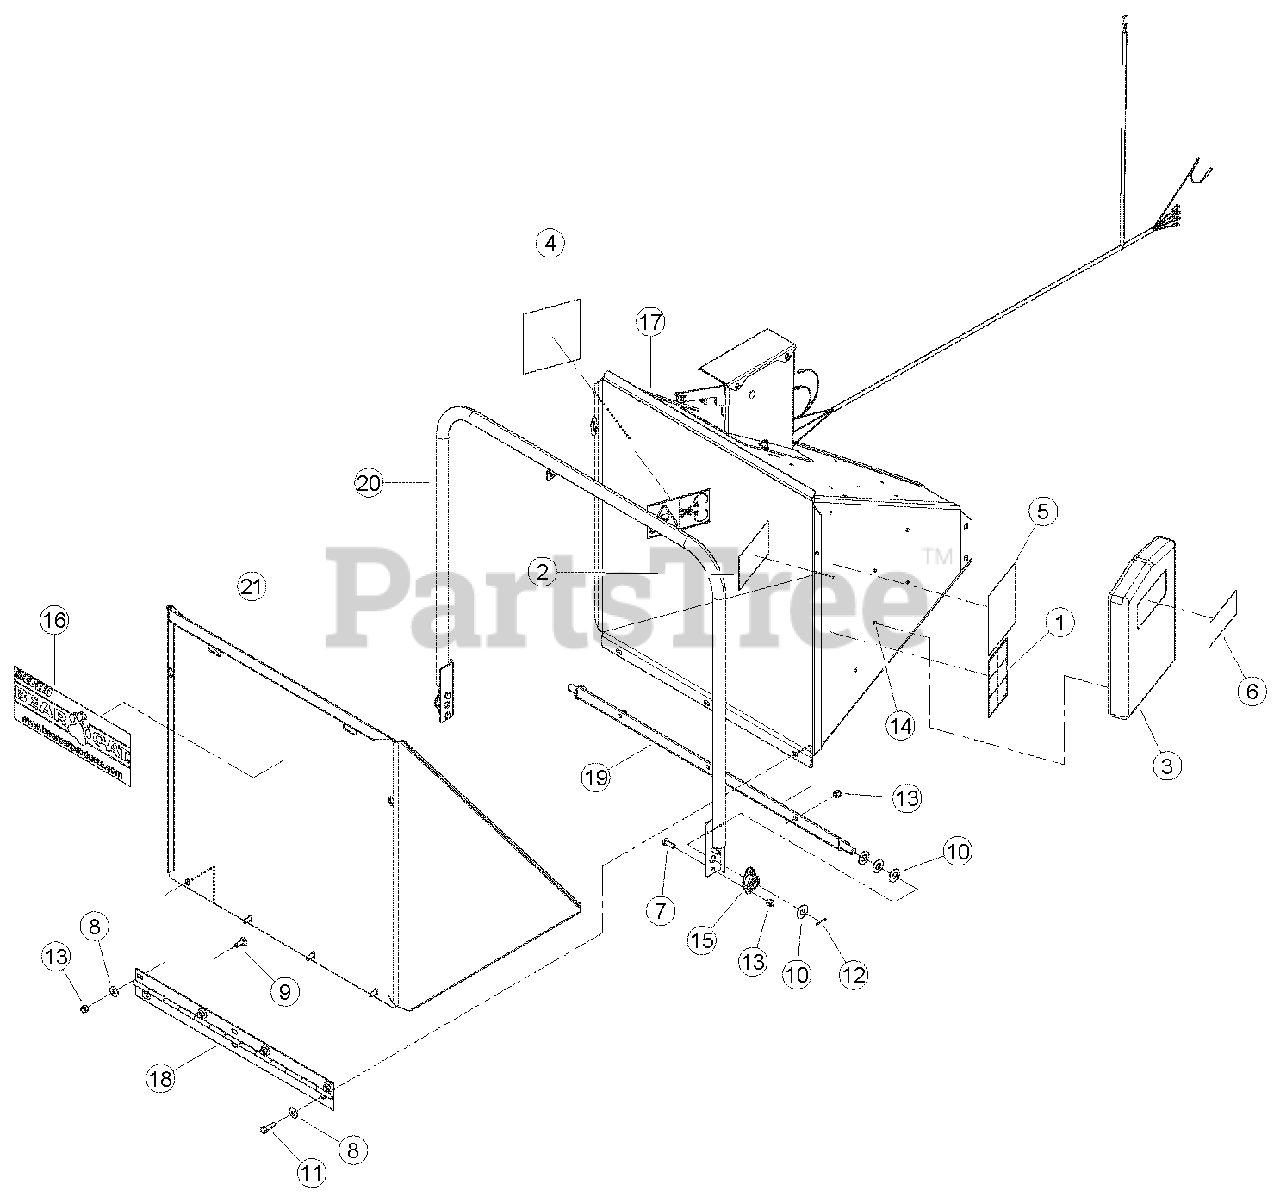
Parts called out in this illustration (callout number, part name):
1	DECAL, OPERATING INSTRUCTIONS ISO
2	DECAL, BLADE DANGER ISO
3	CONTAINER, INSTRUCTION MANUAL
4	DECAL, FEED POSITION
5	DECAL, FEED POSITION
6	DECAL, MUTILINGUAL MANUAL
7	BOLT, 3/8 X 1 HEX HD GR5 ZP
8	WASHER, 3/8 FLAT ZP
9	BOLT, 3/8 X 1 CRG GR5 NC ZP
10	WASHER, 5/8 SAE FLAT ZP
11	BOLT, 3/8 X 1-1/4 HEX HD GR5 ZP
12	PIN, 1/8 X 1.00 ZP COTTER
13	NUT, 3/8 NE NYLOCK ZP
14	RIVET, 1/4 X 1/2 DOME HD BLIND SS
15	BEARING, 5/8 SIDE FLANGE MOUNT
16	DECAL, BEARCAT WEB
18	HINGE, EXTENSION TRAY
19	WELDMENT, CONTROL PIVOT
20	WELDMENT, CONTROL ARM
21	WELDMENT, CHUTE EXTENTION TRAY
